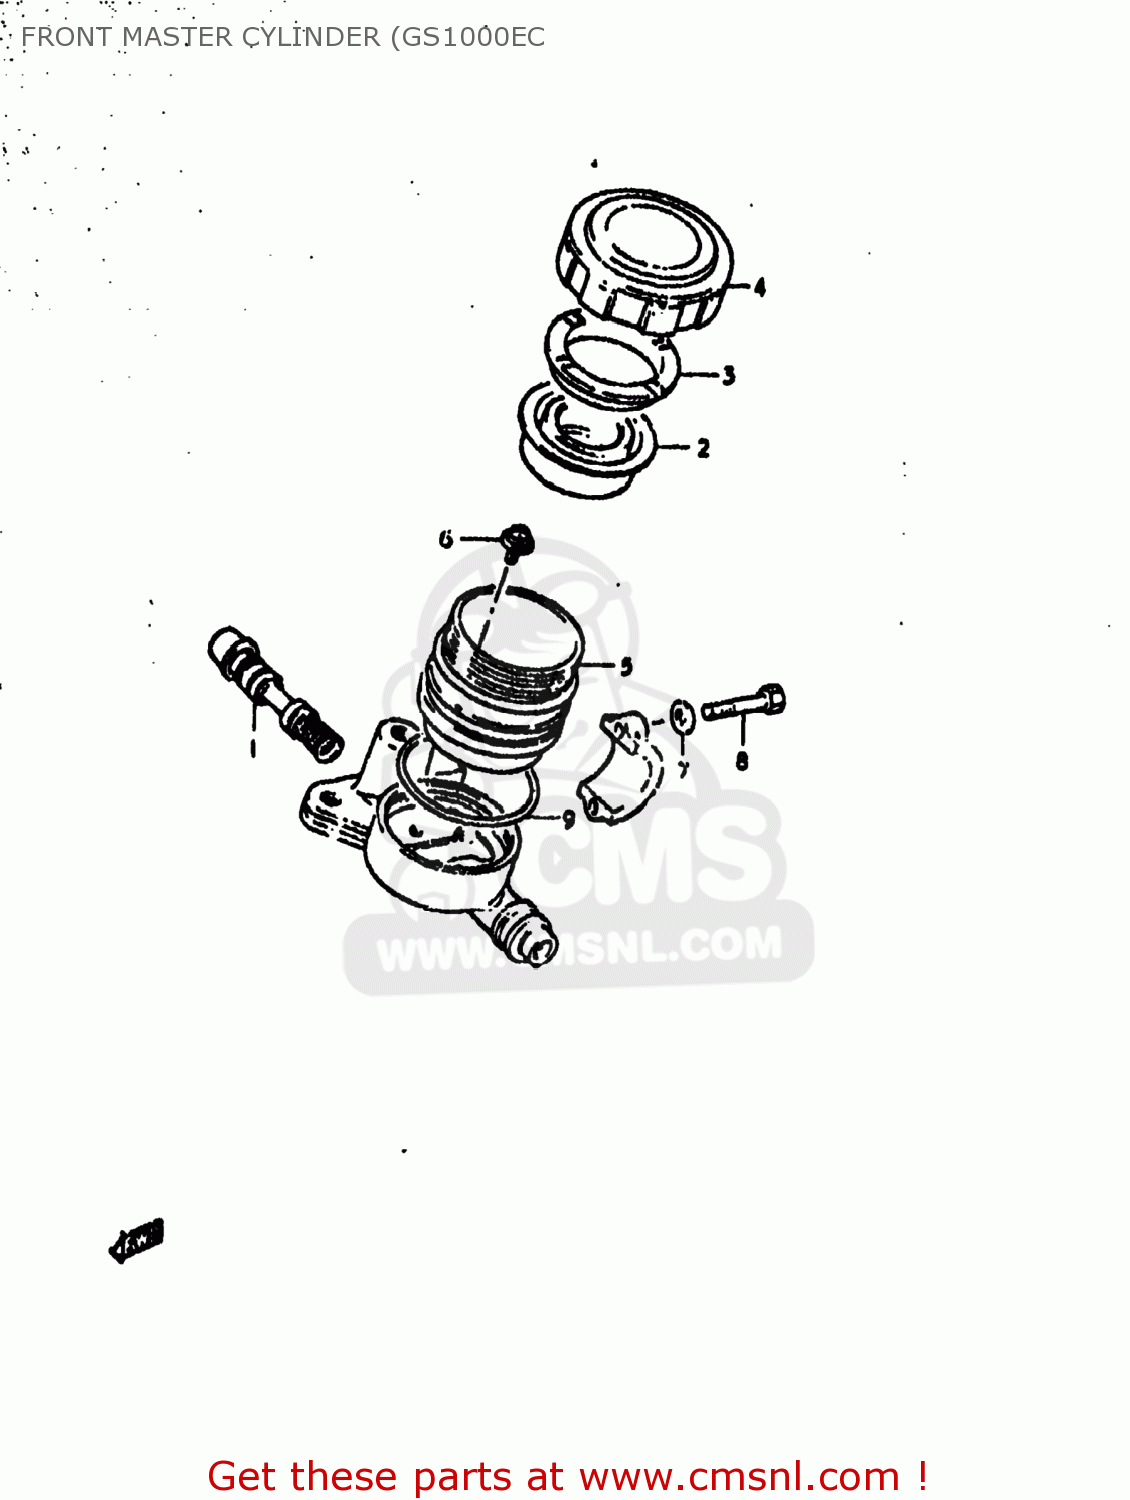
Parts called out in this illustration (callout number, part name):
1	PISTON & CUP SET
2	DIAPHRAGM
3	PLATE
4	CAP,MASTER CYLINDER,REAR
5	RESERVOIR
6	SCREW,MASTER CYLINDER
7	WASHER
8	BOLT
9	O RING
